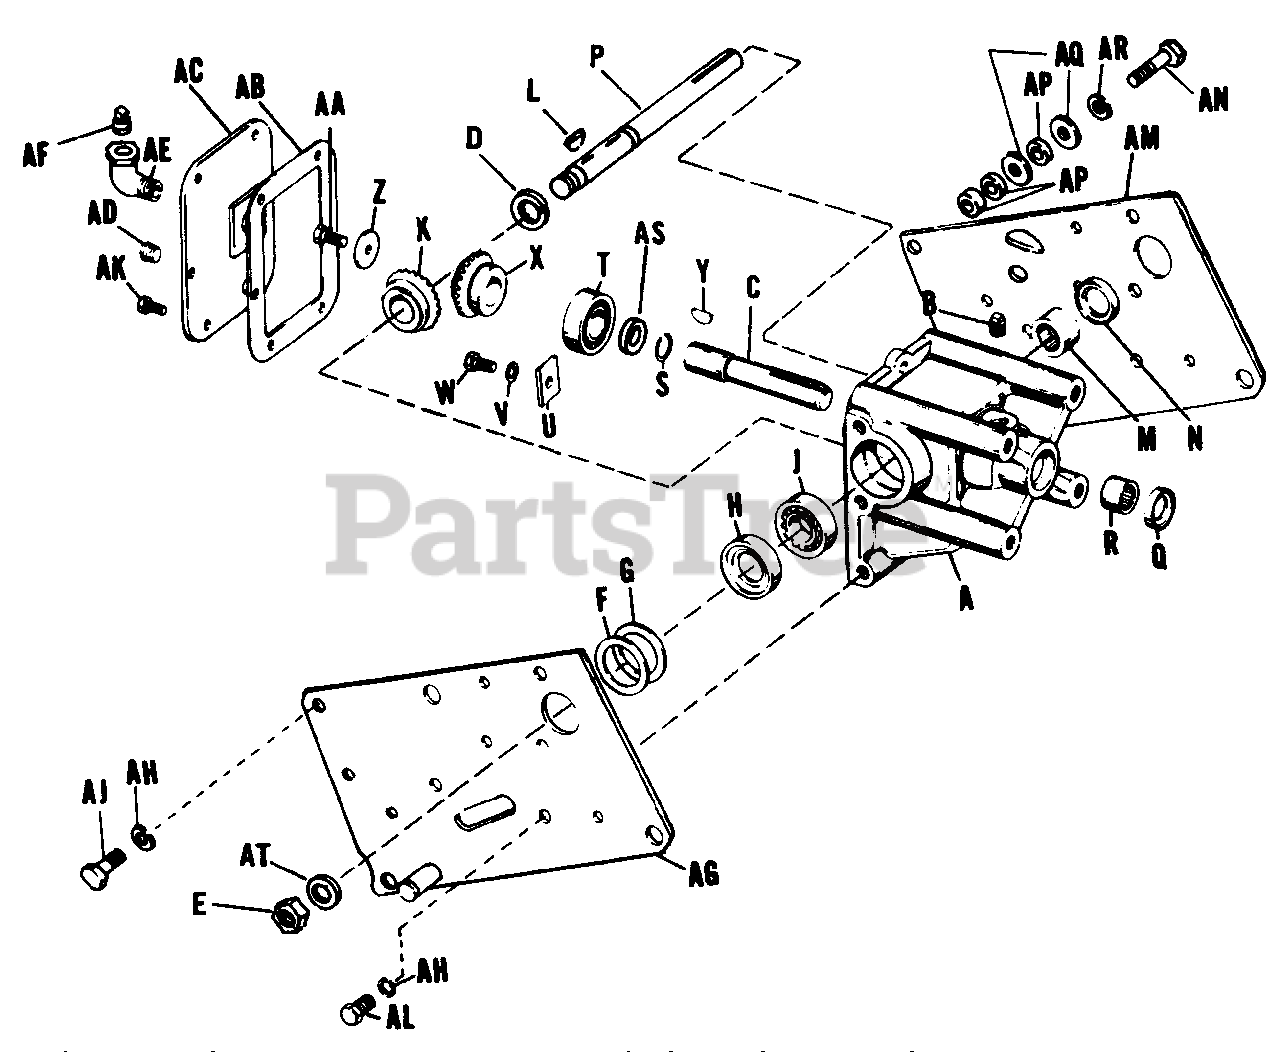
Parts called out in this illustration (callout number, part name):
A	Bevel Gear Housing, W/Bearings
B	Pipe Plug
C	Drive Shaft
D	Retaining Ring
E	Hex Jam Nut, 3/4"-16
F	Shim (As Required)
J	Ball Bearing
K	Bevel Driven Gear
L	Key, Woodruff
M	Needle Bearing
P	Driven Shaft
R	Needle Bearing
S	Retaining Ring
T	Ball Bearing
U	Bearing Clamp Plate
V	Lock Washer, 5/16"
W	Hex Capscrew, 5/16"-18 x 5/8"
X	Bevel Drive Gear
AA	Hex Capscrew, 5/16"-18 x 3/4"
AC	Housing Cover Assy.
AD	Pipe Plug
AE	Street Elbow
AF	Pipe Plug
AG	R.H. Side Plate
AH	Lock Washer, 7/16"
AJ	Hex Capscrew, 7/16"-14 x 1"
AK	Hex Capscrew, 1/4"-20 x 5/8"
AL	Hex Capscrew, 7/16"-14 x 1-1/4"
AM	L.H. Side Plate
AN	Hex Capscrew, 7/16"-14 x 2"
AQ	Washer, 7/16"
AR	Lock Washer, 7/16"
